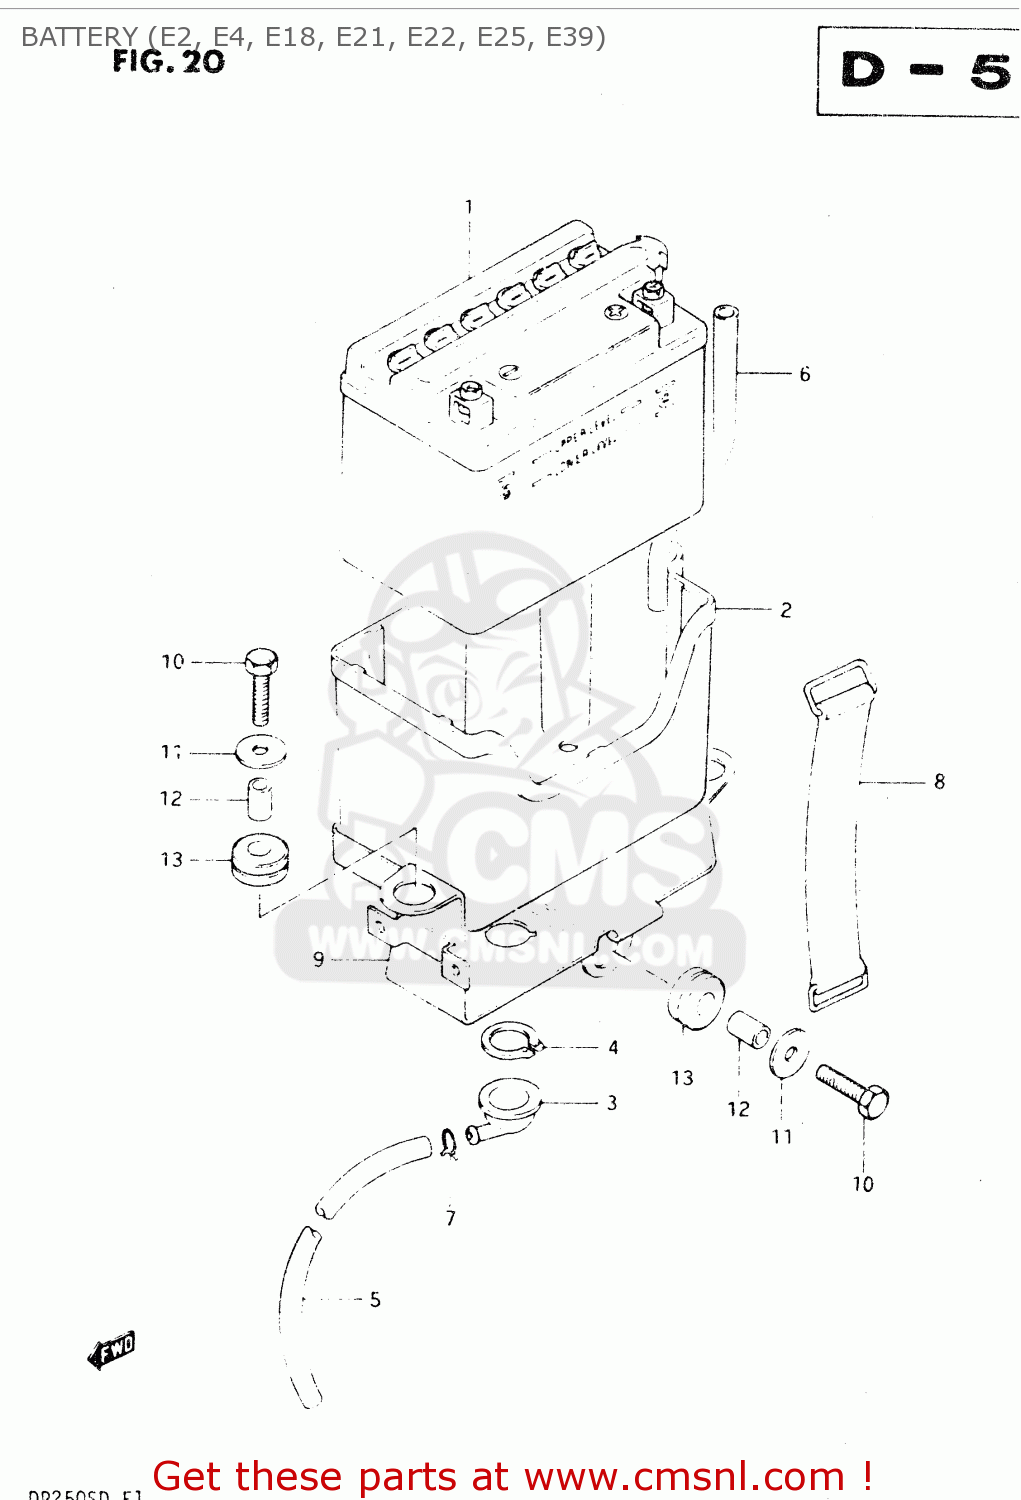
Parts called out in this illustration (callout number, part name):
1	BATTERY ASSY(YB4L-B,12V4.2AH)
2	CASE, BATTERY
3	FUNNEL,BATTERY EXHAUST
4	CIRCLIP
5	HOSE,BATTERY EXHAUST
6	HOSE, EXHAUST (L:45)
7	CLIP
8	BAND
9	HOLDER, BATTERY
10	BOLT, UPPER
11	WASHER (6.5X20X1.2)
12	SPACER(6.1X9X7.5)
13	CUSHION
